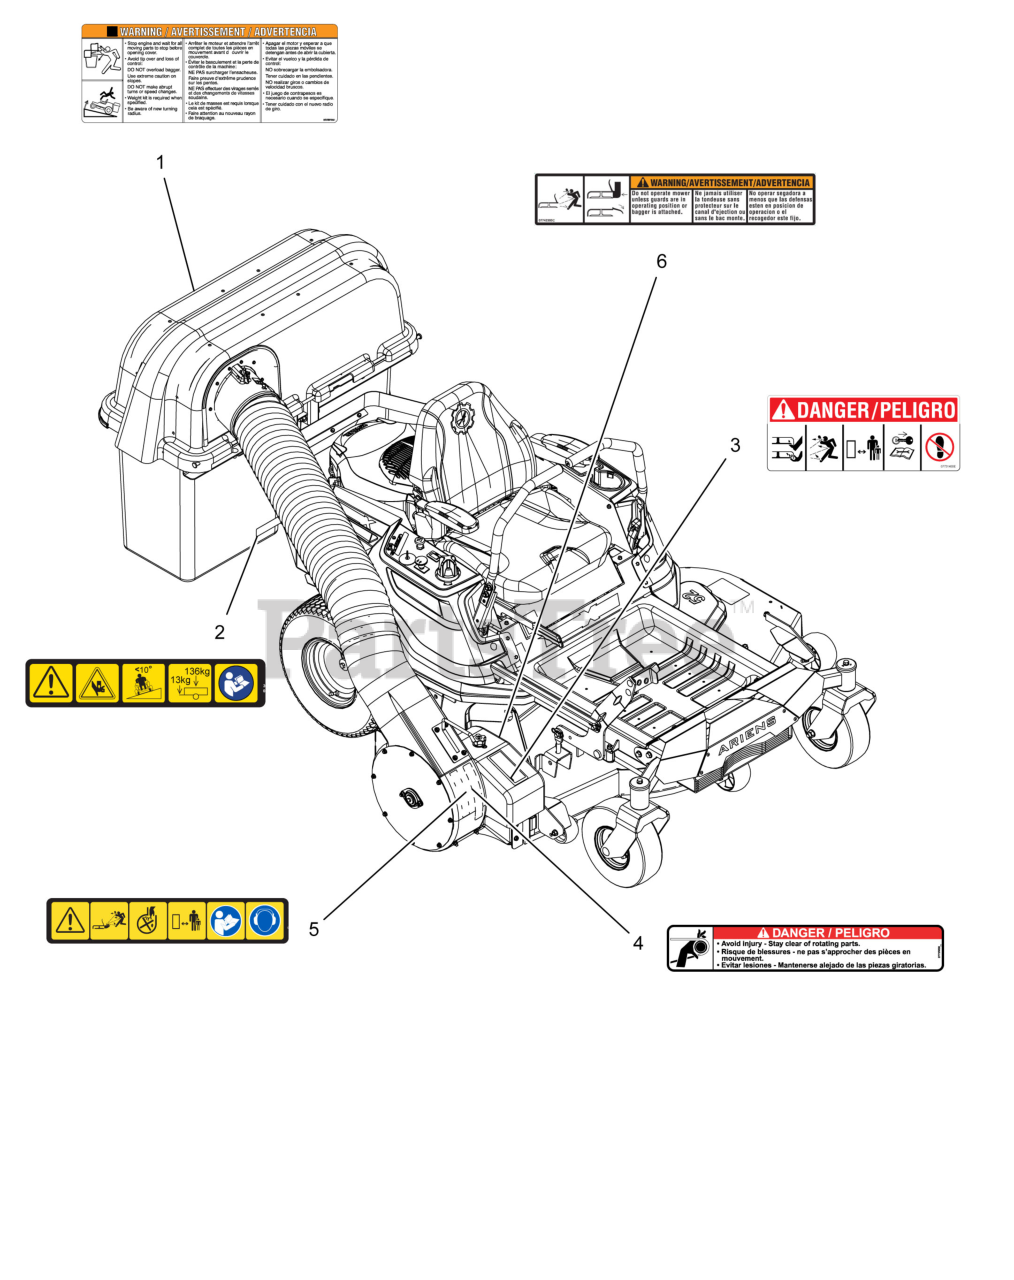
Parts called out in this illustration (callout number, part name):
1	DECAL, BAGGER COVER
2	DECAL, TRAILER HITCH
3	DECAL, MOWER PAN DANGER
4	DECAL- DANGER
6	DECAL, WARNING
